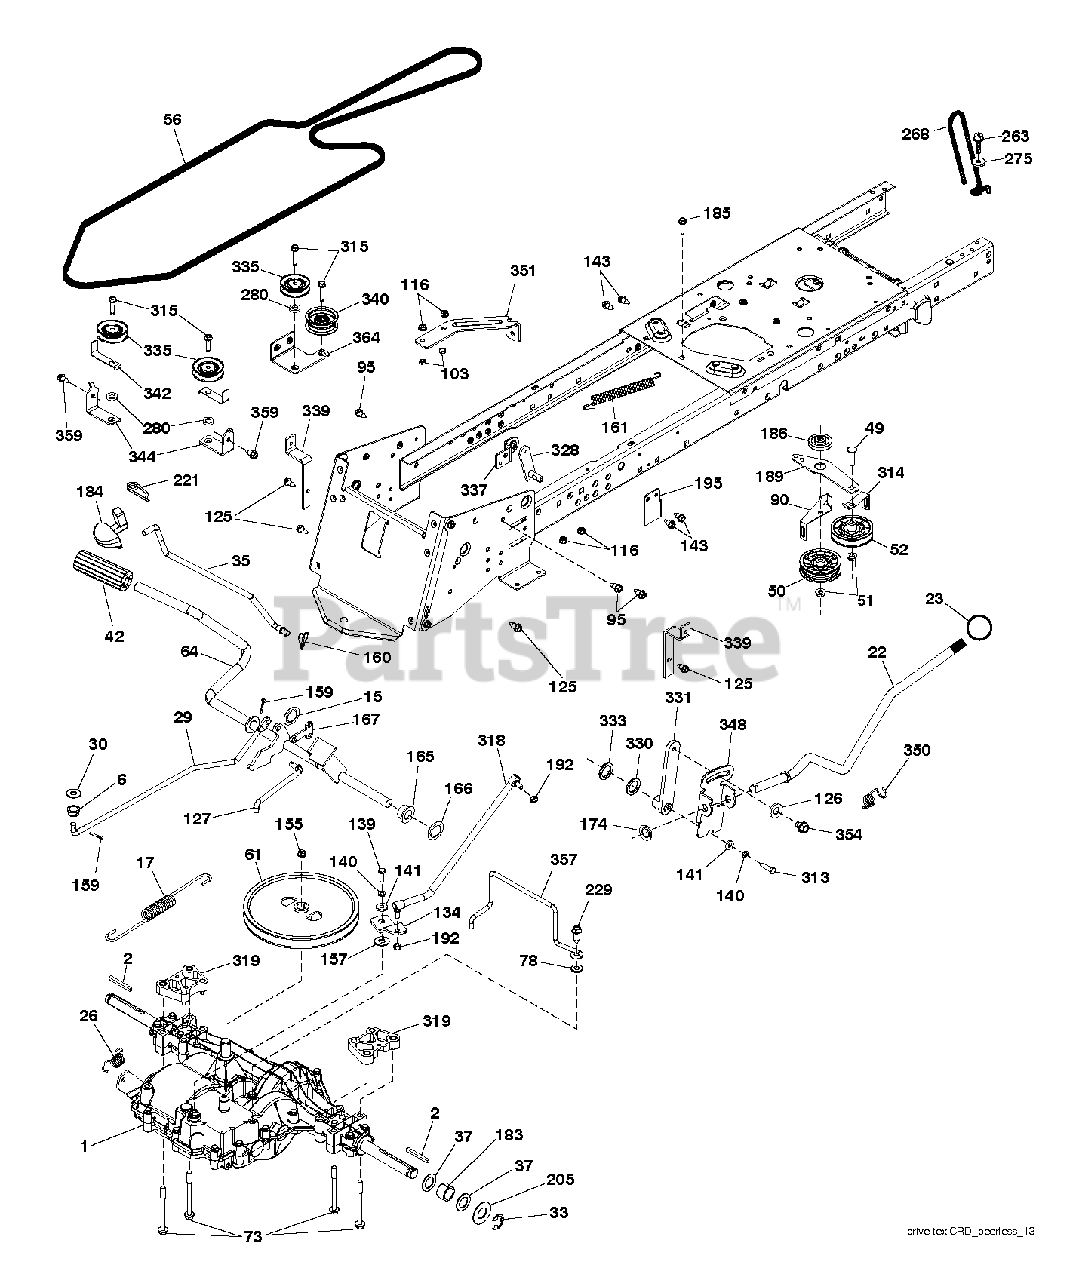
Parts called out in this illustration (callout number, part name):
2	SQUARE KEY
6	MANDREL ASS'Y
23	KNOB.DUCKHEAD.1/2
26	SPRING,BRAKE RETURN
33	E-RING LT
35	ROD, BRAKE, PARK
42	PEDAL COVER T
49	BOLT
51	NUT LOCK FLG 3/8-16 UNC
52	IDLER.V-GROOVE.910.OFFSET
64	SHAFT.ASM.PEDAL.BRAKE.
73	BOLT.HEX.FLNG.5/16-18X3.75
78	WASHER
95	SCREW, 3/8-16X3/4
103	JAM NUT TI
116	NUT LOCK HEX FLANGE 5/16-18
125	SCREW
126	WASHER.SRRTD.5/16
127	LINK.CLUTCH.GROUND.DRIVE
134	ARM SHIFT
139	BOLT 1/4-28X3/4
140	LOCKWASHER
141	WASHER LT
155	RETAINING RING LT
157	WASH-SHFT PLT LT
159	COTTER PIN
160	RETAINER CLIP
161	SPRING, RETURN LT
165	BUSHING.SHAFT.BRAKE.HAND
166	NUT.PUSH.625
167	LATCH.BRAKE.SPRING
174	NUT.PUSH.500.2006
183	SPACER AXLE
184	HANDLE.PARKING.BRK.PRED.LT.RED
186	SPACER.RETAINER
192	NUT LOCK CENTER 1/4 -28 FNTHD
221	RETAINER.SPRING.CLIP.H
229	SCREW 5/16-18X1
263	SCREW, 3/8-16X3/4
275	WASHER
314	RETAIN BELT
315	BOLT.5/16-18X1.25
330	WASHER.NYL.7/8IDX.105"HYD CR
335	PULLEY.V-IDLER.
359	SCREW LT.3/8-46X5/8
